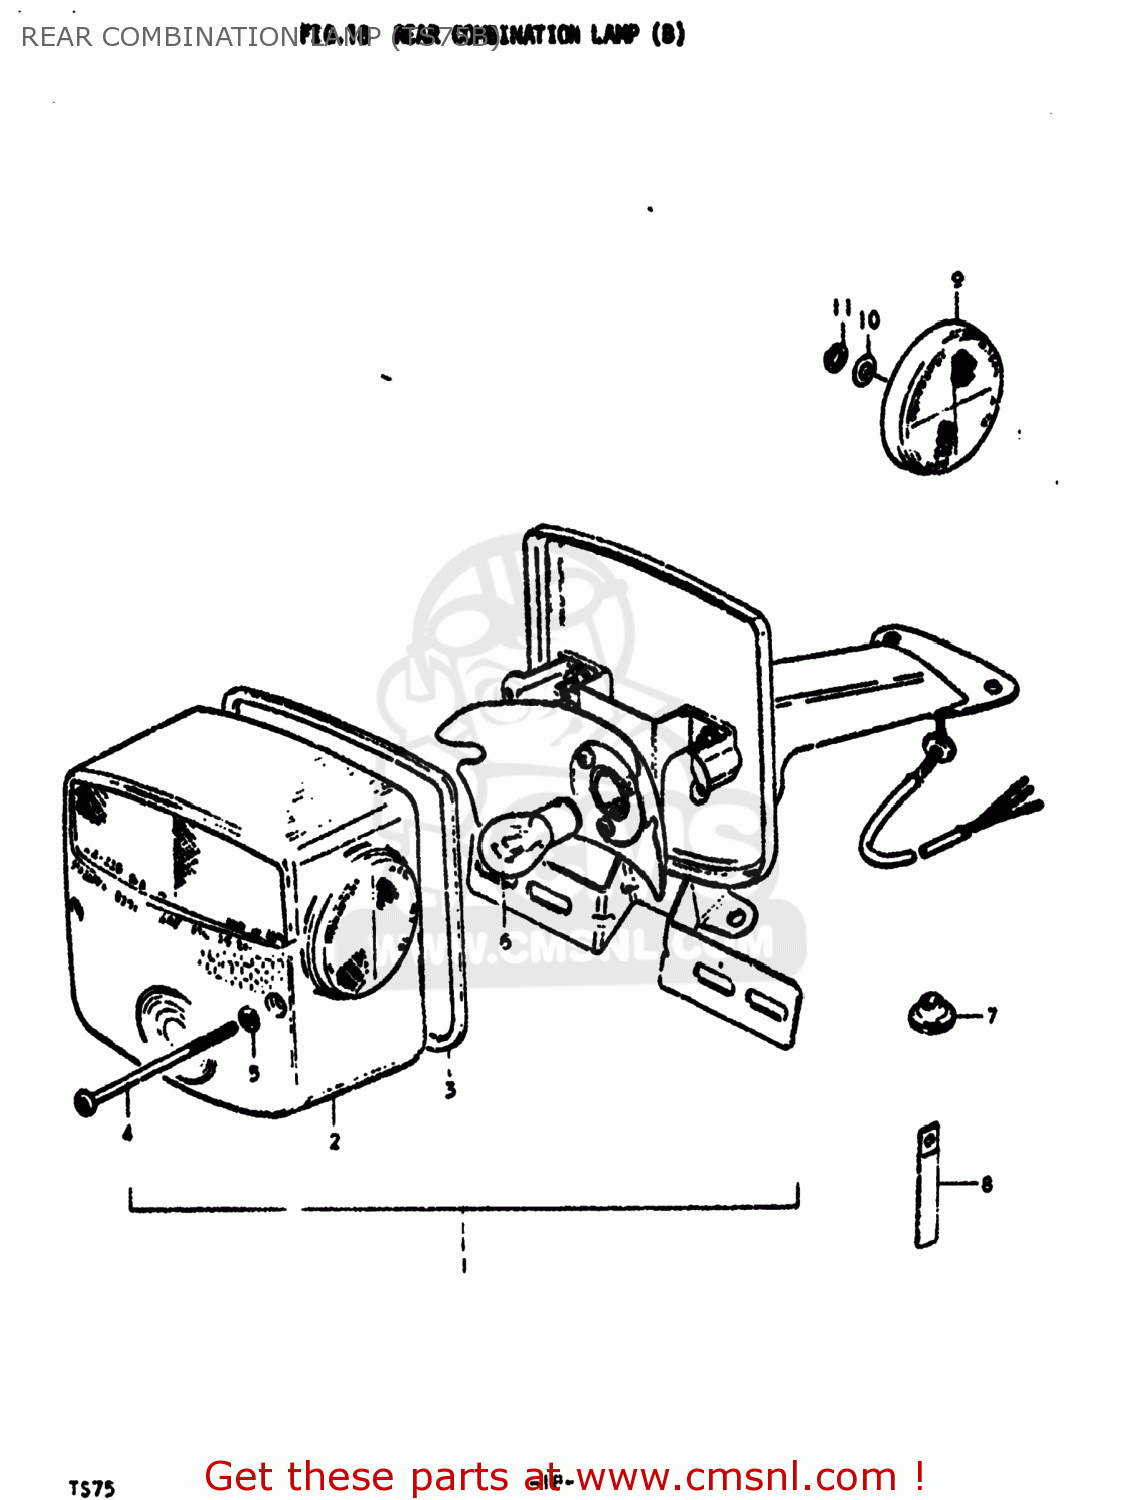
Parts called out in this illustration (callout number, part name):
1	LAMP ASSEMBLY,REAR COMBINATION
2	GASKET (NAS)
3	GASKET (NAS)
4	SCREW
5	GASKET (NAS)
6	BULB(6V32/3CP,STANLEY)
7	GROMMET
8	CLAMP
9	REFLEX REFLECTOR,FR
10	WASHER
11	LOCK WASHER
